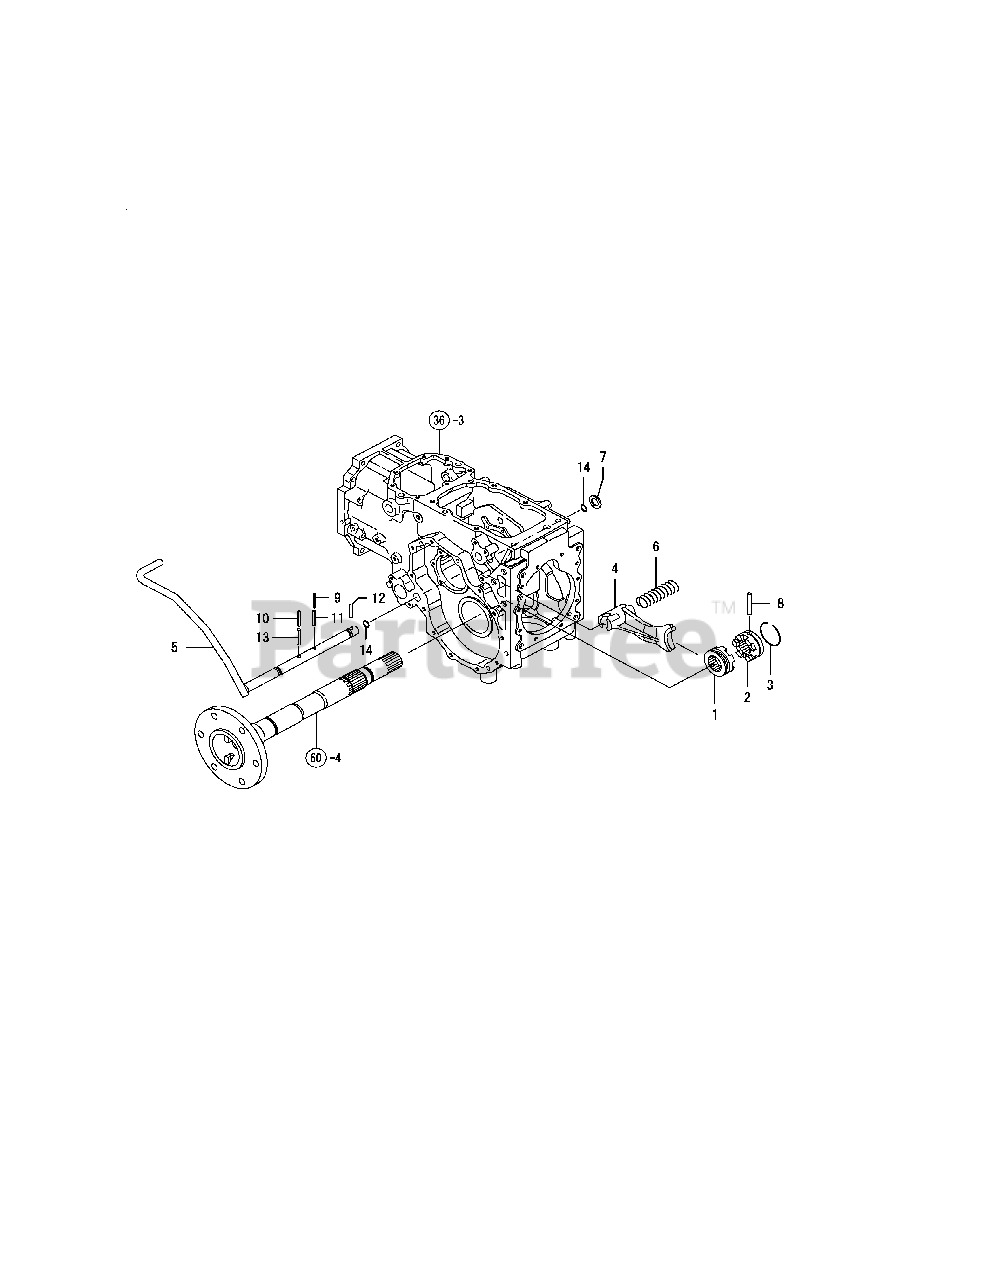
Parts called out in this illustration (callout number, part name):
1	SLIDER, DIFFERENTIAL
2	SLIDER, DIFFERENTIAL
5	PEDAL, DIFFERENTIAL
7	SPACER 20X32X3.2
9	SPRING PIN 3.5X40
10	SPRING PIN 5X40
11	SPRING PIN 6X40
12	SPRING PIN 8X32
13	SPRING PIN 8X40
14	O-RING 1A P-15.0
